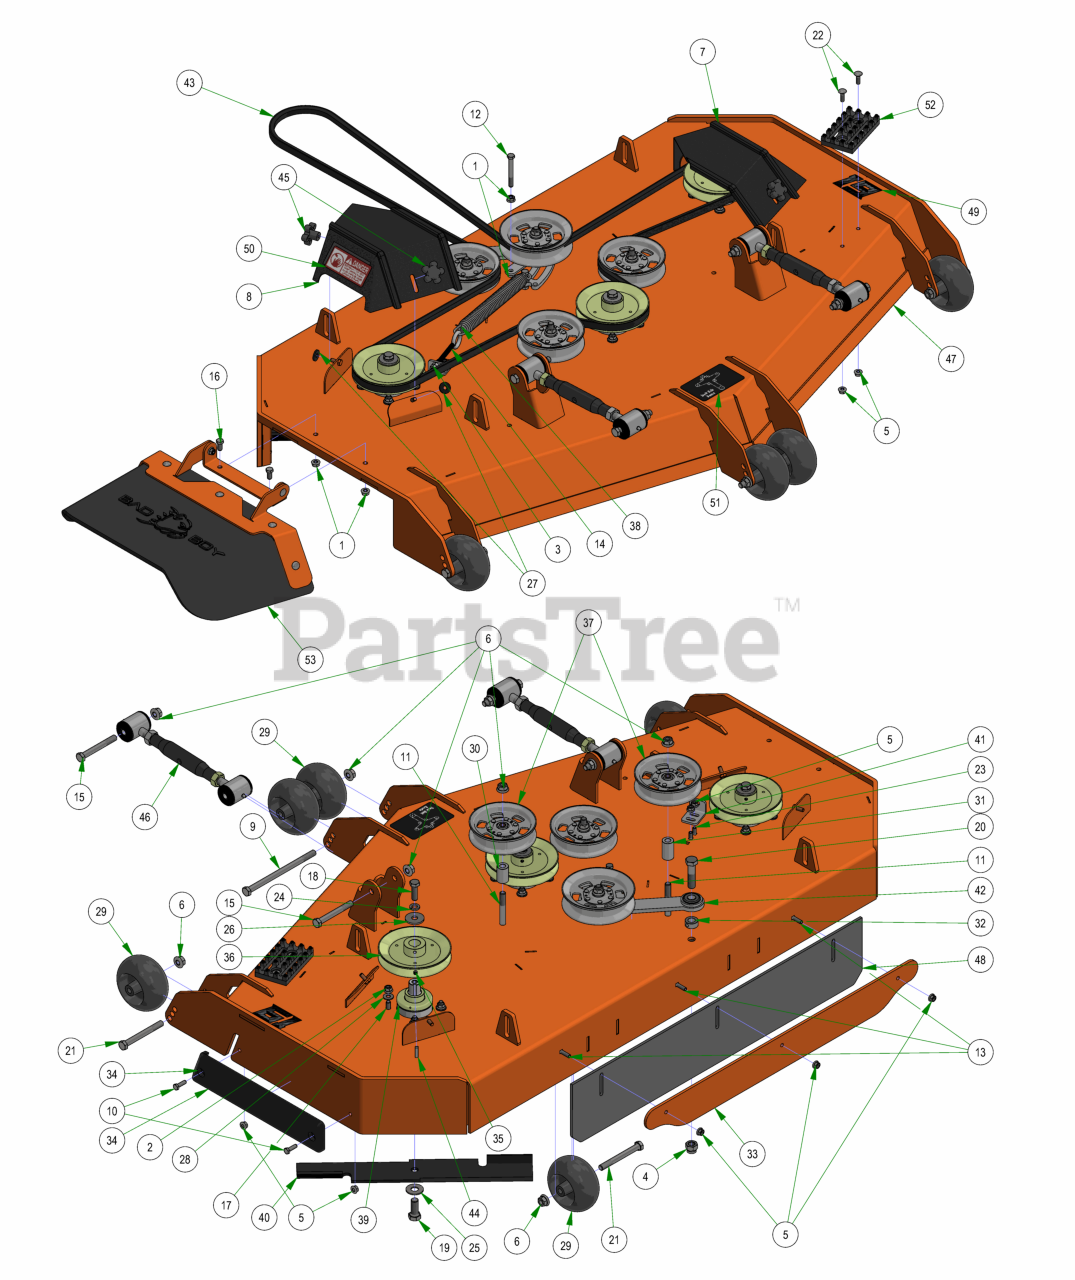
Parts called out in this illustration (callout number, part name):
1	3/8-16 HEX SERRATED FLANGE NUT HARD/ZINC
2	3/8-16 NYLON INSERT FLANGE LOCKNUT (GR.F) ZINC
3	3/8-16 HEX NUT ZINC
4	5/8-11 NYLON INSERT LOCKNUT ZINC
5	5/16-18 NYLON INSERT FLANGE LOCKNUT ZINC
6	1/2-13 NYLON INSERT FLANGE LOCKNUT ZINC
7	2019 61" Outlaw Gen2 Pulley Cover Left
8	2019 61" Outlaw Gen2 Pulley Cover Right
9	1/2-13 X 8 HEX CAP SCREW GR 5 ZINC
10	5/16-18 X 1 HEX CAP SCREW (GR.5) ZINC
11	1/2-13 X 3-1/2 HEX FLANGE BOLT (GR.8) ZINC
12	3/8-16 X 3 HEX CAP SCREW (GR.5) ZINC
13	5/16-18 X 1-1/4 CARRIAGE BOLT ZINC
14	4" 3/8-16 Eye Bolt
15	1/2-13 X 4 HEX CAP SCREW (GR.8) ZINC YELLOW
16	3/8-16 X 3/4 HEX CAP SCREW (GR.5) ZINC
17	3/8-16 X 1-1/2 HEX CAP SCREW (GR.5) ZINC
18	1/2-20 X 1-1/2 HEX CAP SCREW (GR.5) ZINC
19	5/8-18 X 1-1/2 HEX CAP SCREW (GR.8) ZINC YELLOW
20	5/8-11 X 2-1/2 HEX CAP SCREW (GR.5) ZINC
21	1/2-13 X 4-1/2 HEX CAP SCREW (GR.5) ZINC
22	5/16-18 X 1 CARRIAGE BOLT (GR.8) ZINC
23	5/16-18 X 7/8 CARRIAGE BOLT ZINC
24	1/2 SPLIT LOCKWASHER (GR.8) ZINC/YELLOW
25	5/8 USS FLAT WASHER (1-3/4" OD) GR.8 ZINC YELLOW
26	1/2 BELLEVILLE WASHER (1-5/8 OD X .140 THK) ZINC
27	.360 ID X .983 OD X .120 THICK FLAT WASHER NYLON BLACK
28	5/16 USS FLAT WASHER (7/8 OD) ZINC
29	2019 Deck Wheel
30	.502 ID X .750 OD X 1.500 Long Spacer
31	1 3/4" Pulley Spacer
32	5/8 SOLID SHAFT COLLAR (W/1 SET SCREW) ZINC
33	61 Bolt in Baffle Deck v2 Stripping Plate
34	REVISED TRIM BUMPER_20180226
35	5/16-24 X 1/4 SOCKET SET SCREW (CUP PT) PLAIN
36	6 1/4" Drive Pulley
37	5-3/4 Idler Pulley
38	2019 Outlaw Gen2 Deck Spring
39	OUTLAW SPINDLE ASSEMBLY
40	61 inch Fusion Blade
41	2019 Deck Eye Bolt Tab
42	2019 Rebel Rogue Deck Idler
44	1/4 X 1 SQ MACHINERY KEY 1018 STL PLN
45	5/16" Knob
46	Turnbuckle Assembly (M20-2.5)
47	2019 Sloped 61" Deck
48	R Series Rubber For Deck
49	61" Deck Decal
50	Danger Decal-Spindle/Discharge
51	2019 Rebel & Rogue Deck Belt Route Decal
52	Deck Step Assembly
53	2019 Outlaw Gen2 Chute Assembly
